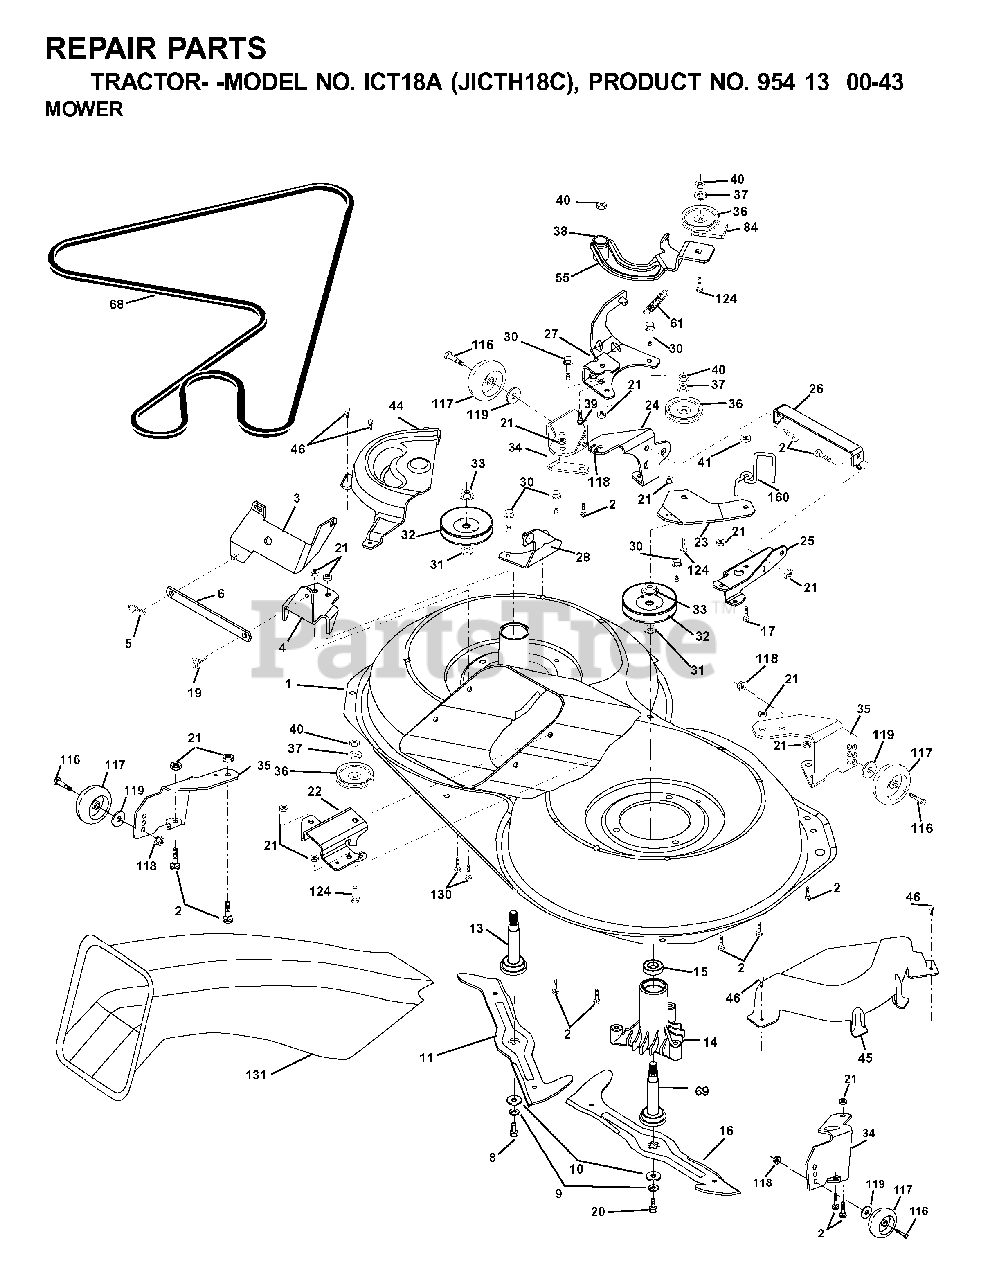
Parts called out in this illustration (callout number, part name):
2	BOLT
3	BRACKET
5	RETAINER-SPRNG RB
6	BAR SWAY
8	BLADE BOLT
9	LOCKWASHER
10	WASHER.BLADE
11	BLADE, LH (CTH150)
13	SHAFT ASM VENT
14	HSG MANDREL
16	RP BLADE RH (CTH150)
17	BOLT.3/8-14X1.25
19	BOLT SHD 5/16-18
21	LOCKNUT
22	BRACKET
23	BRACKET
26	BRACE
27	BRACKET
30	SCREW THDROL ROLLING WASHER HD
31	WASHER
33	NUT
36	PULLEY.IDLER.4.25
40	LOCKNUT
41	NUT LOCK FLG 3/8-16 UNC
45	MANDREL COVER RH
46	SCREW.1/4-20X5/8
55	ARM IDLER
68	HEX-BELT 107 MOWER
69	SHAFT.ASM.W/LWR.BRG.RH.THREAD
84	KEEPER, BELT IDLER
116	BOLT, SHOULDER
117	WHEEL GAGE DONUT
118	LOCKNUT
119	WASHER
124	BOLT.3/8-16X1.50
131	CHUTE BAGGER
